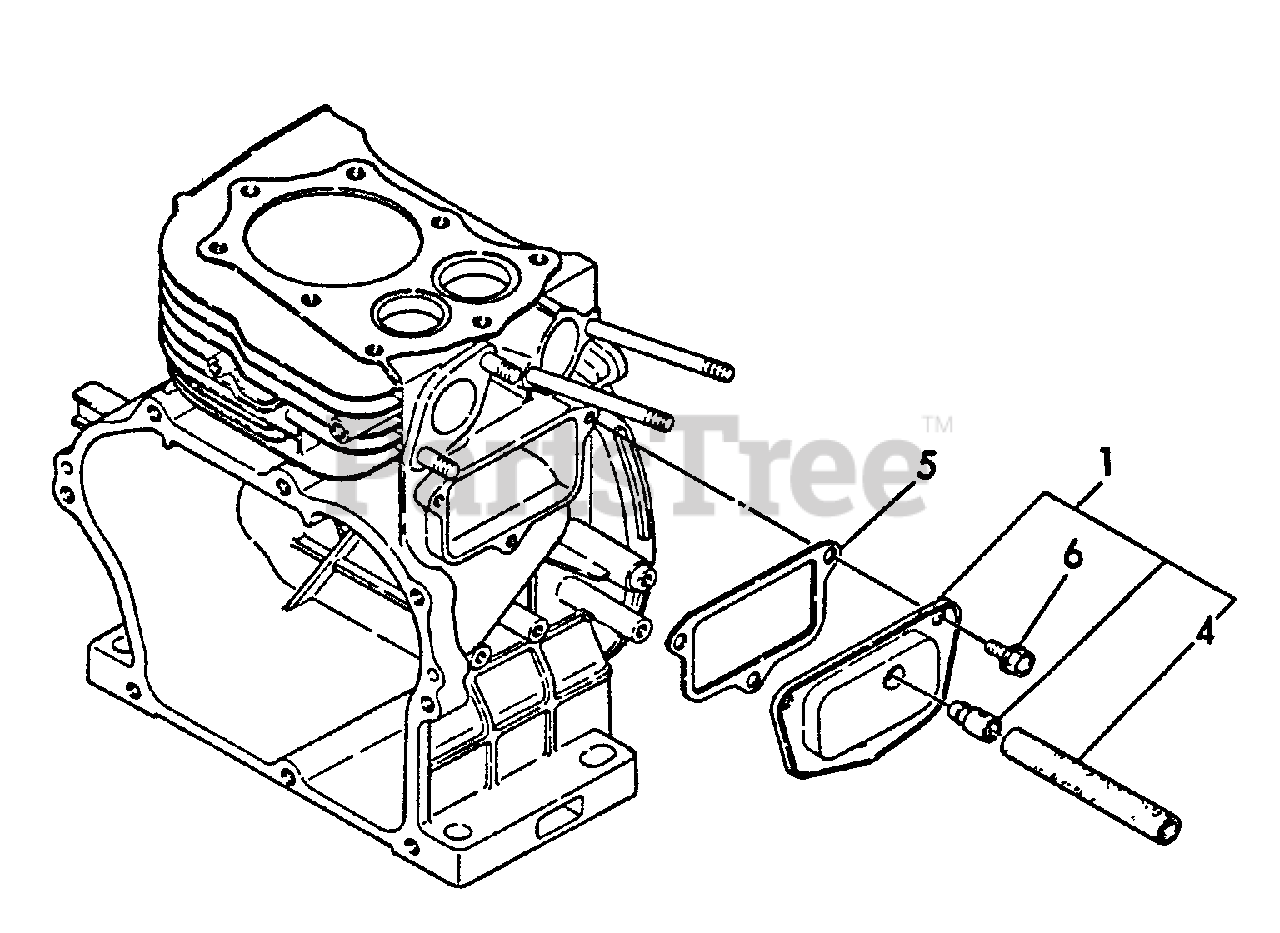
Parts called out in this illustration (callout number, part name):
1	VENT, FUEL TANK
4	PIPE - BREATHER
5	GASKET, BREATHER
6	BOLT - 6X8 -- PLATED
